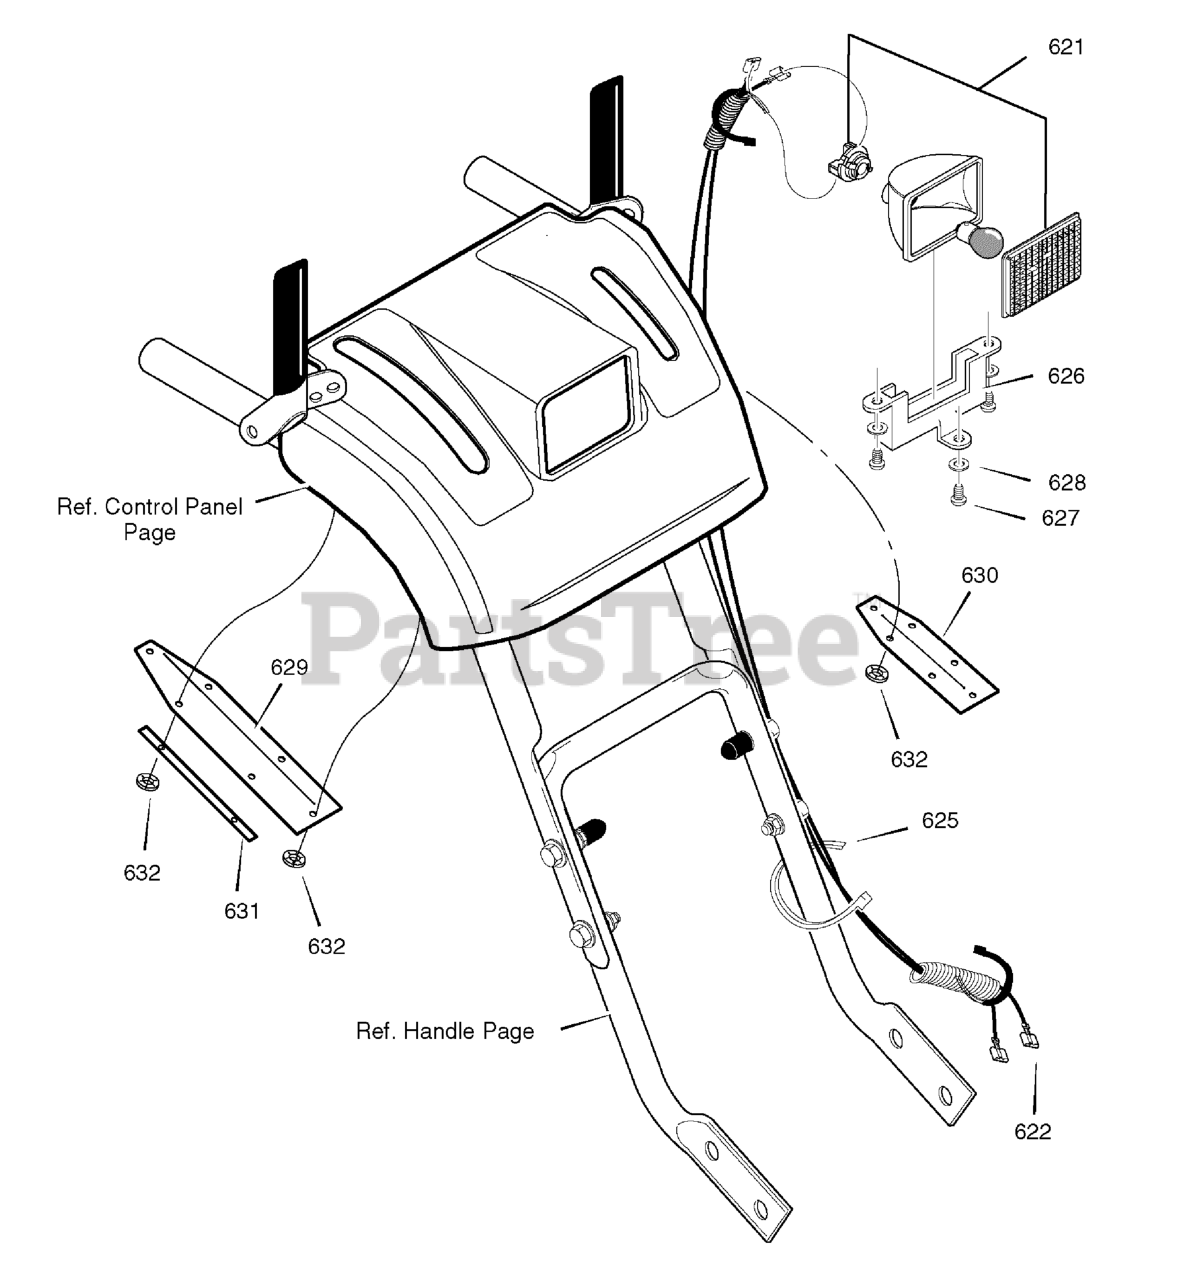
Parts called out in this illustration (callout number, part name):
621	LIGHT, HALOGEN
622	HARNESS, WIRE
625	TIE, CABLE
626	BRACKET, LIGHT
627	SCREW #8 X 0.50
628	WASHER, FLAT
632	NUT, PUSH
